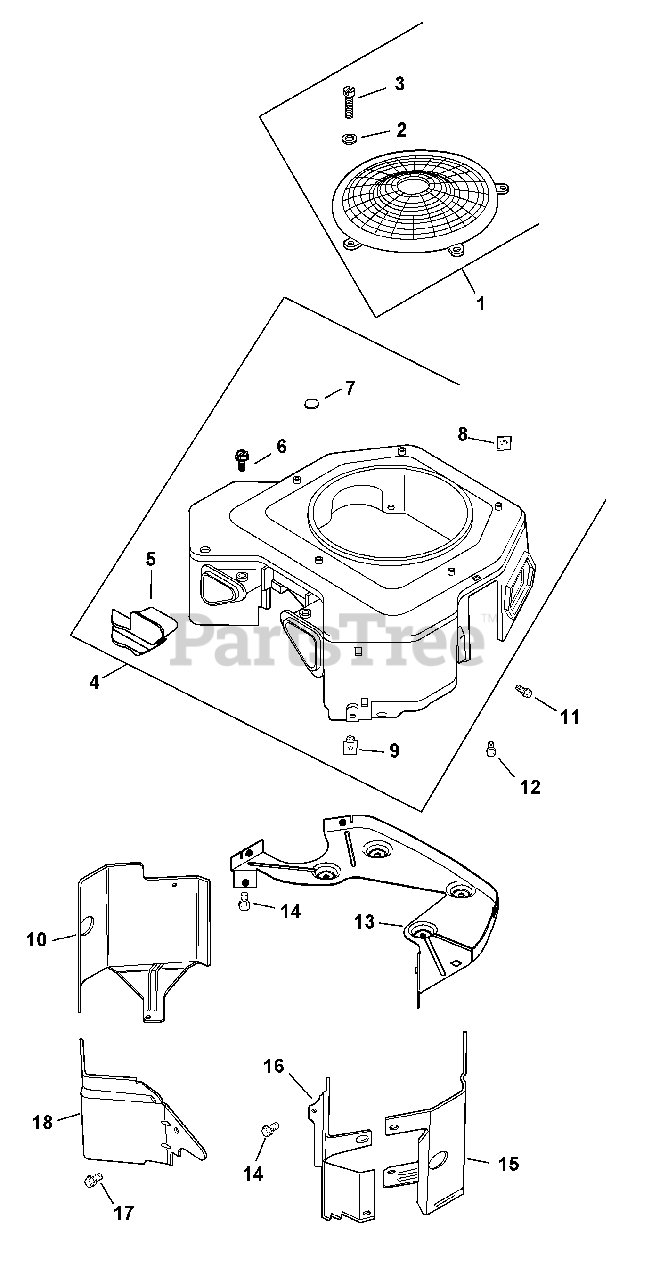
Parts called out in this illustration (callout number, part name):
1	Kit, Guard
2	Washer, Flat 7/32
3	Screw, Lbd Skt Pan M5x0.8x10
4	Kit Blower Housing Assembly
5	Cover, Blower Housing-Molded
6	Screw, WSH HD Tap #8-18 x 1/2"
7	Plug, Button 9/16
10	Kit, Cyl Barrel - #1 Side
11	Screw, Flg Thd Frm M5x0.8x16
12	Screw, Flg Thd Frm M5x0.8x20
13	Kit, Backing Plate (Inc. M-545016-S)
14	Screw, Flg Thd Frm M6x1.0x16
15	Kit, Cyl Baffle - #2 Side
16	Baffle, Valley #2 Side
17	Screw, Flg Thd Frm M5x0.8x10
18	Baffle, Valley #1 Side
